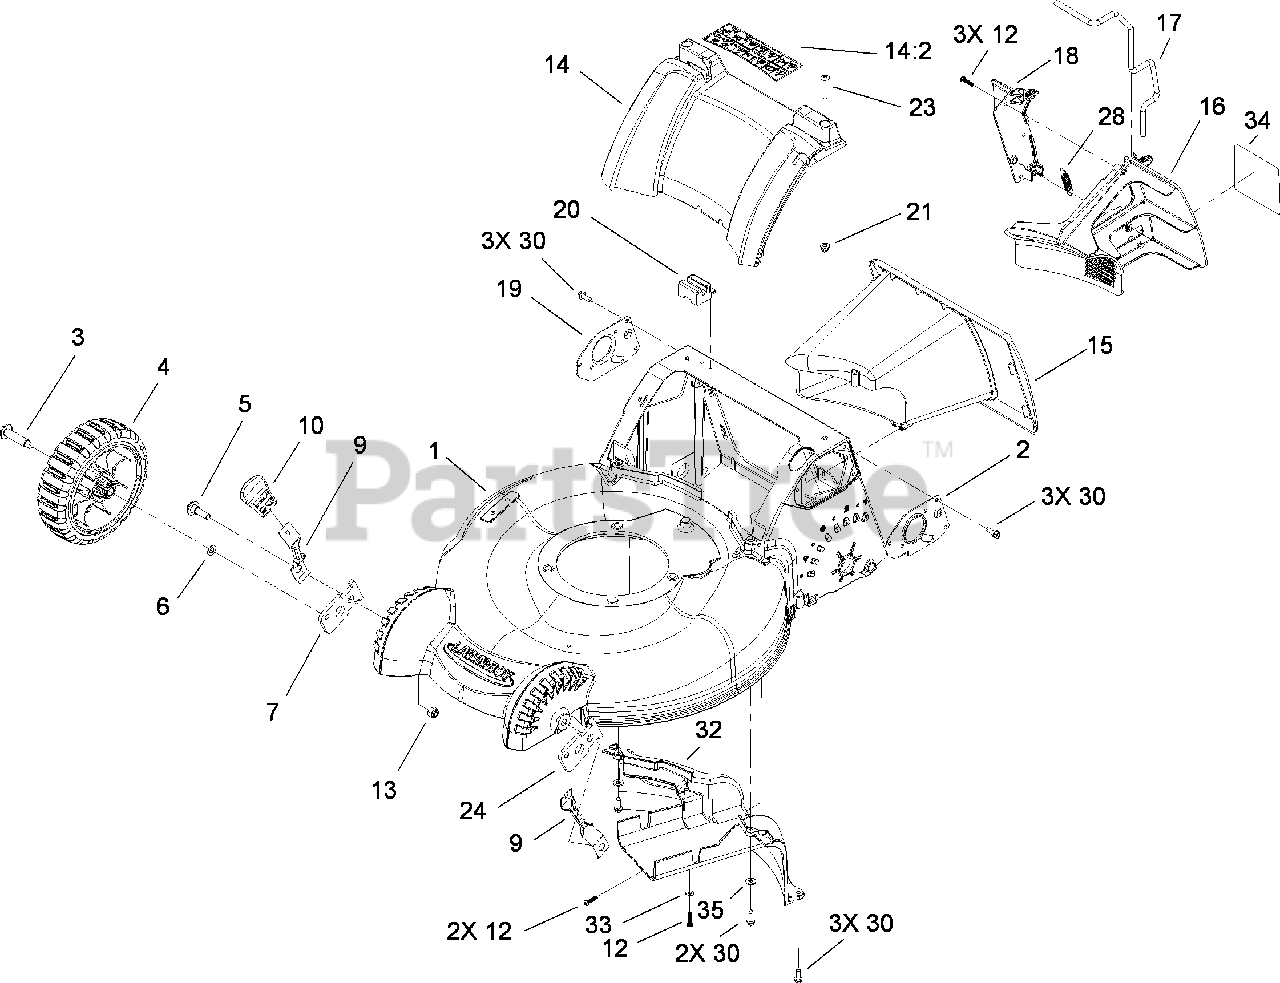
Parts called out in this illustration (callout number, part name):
1	HOUSING ASM
2	MOUNT-HANDLE, LH
3	BOLT-SHOULDER
4	8 INCH WHEEL ASM
5	BOLT-SHOULDER
7	ARM-PIVOT, RH
9	ARM-SPRING, FRONT
12	SCREW-PLASTITE
13	NUT-LOCK, NI
14	COVER-REAR
14:2	DECAL-WARNING
16	PLUG-MULCH, LH
17	LATCH-MULCH PLUG
18	PLUG-MULCH, RH
19	MOUNT-HANDLE, RH
20	MODULE-SWITCH
21	NUT-CLIP
23	SCREW-PTH
24	ARM-PIVOT, LH
28	SPRING-EXTENSION
30	SCREW-HWHTF
32	BAFFLE-REAR
33	WASHER-FLAT
34	DECAL-MULCH PLUG
35	WASHER-FLAT
